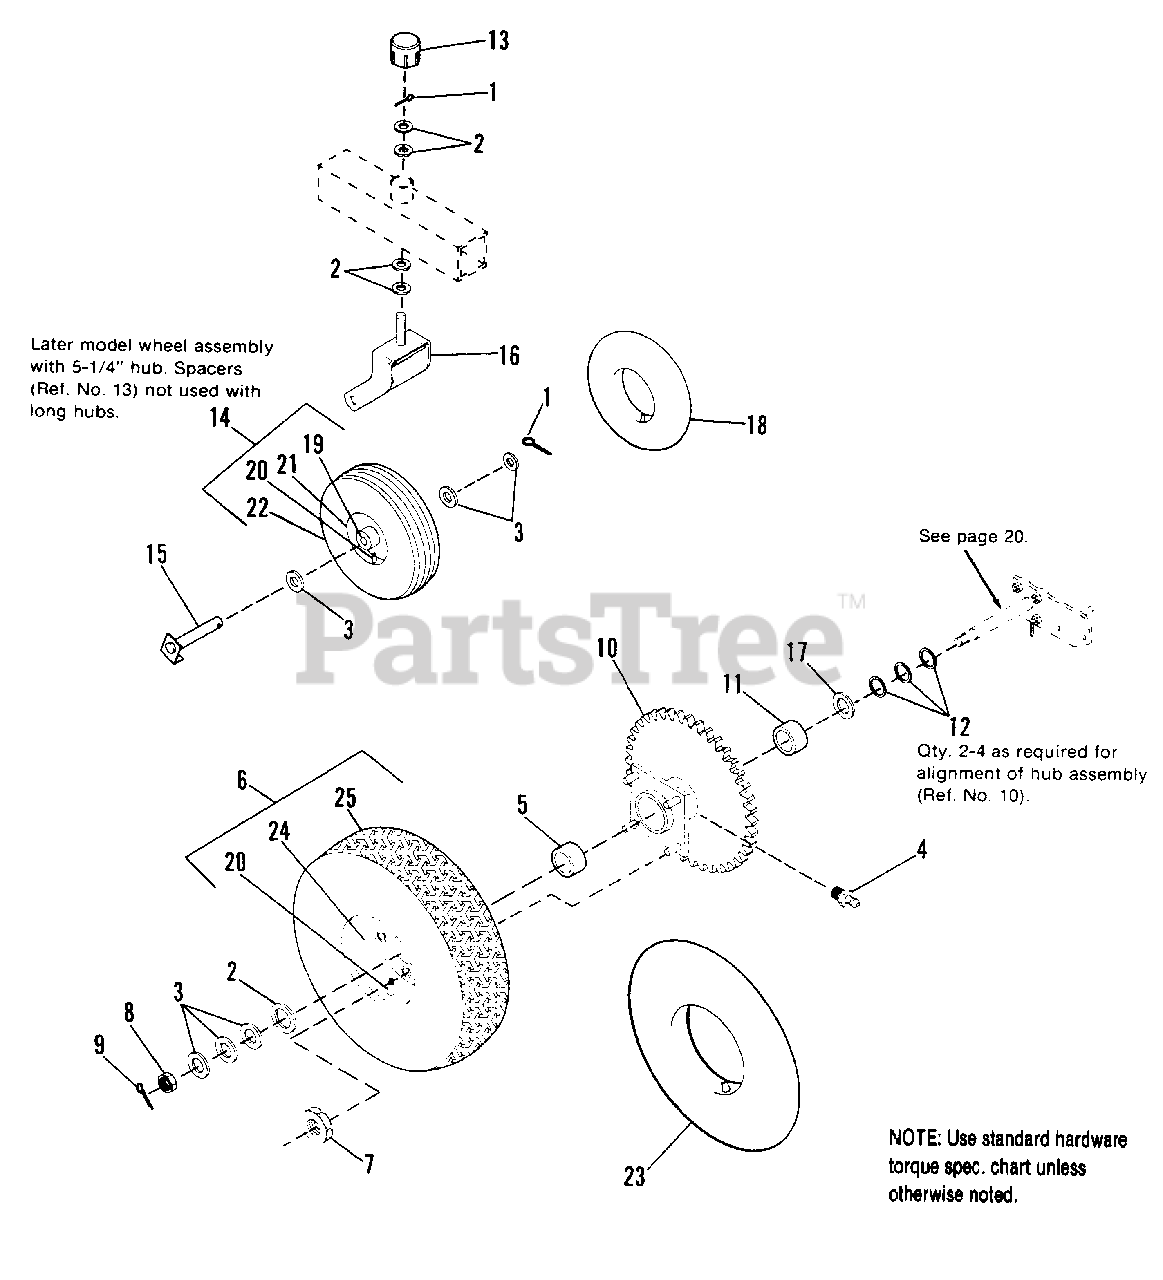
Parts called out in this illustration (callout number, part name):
1	COTTER PIN
2	WASHER, Plain
3	WASHER, Plain
4	FITTING, Grease
6	WHEEL AND TIRE ASSY., 18 x 9.50-8 (Incl. Ref. Nos. 20 (Qty. 2), 23, 24 & 25)
7	NUT, Wheel, 7/16-20
8	NUT, Hex, Slotted, 3/4-16
10	HUB ASSY.
12	WASHER, Plain (As required for alignment)
13	CAP, Threaded
14	WHEEL AND TIRE ASSY., 13 x 5.00-6 (Incl. Ref. Nos. 18, 19, 20 (Qty. 1), 21 & 22)
15	AXLE PIN ASSY.
16	CASTER ASSY.
17	WASHER, Plain
18	* TUBE (Used with Ref. No. 14)
19	BEARING, Flanged
20	VALVE STEM
21	WHEEL ASSY.
22	TlRE, 13 x 5.00-6
23	* TUBE (Used with Ref. No. 6)
24	WHEEL ASSY.
25	TIRE, 18 x 9.50-8
